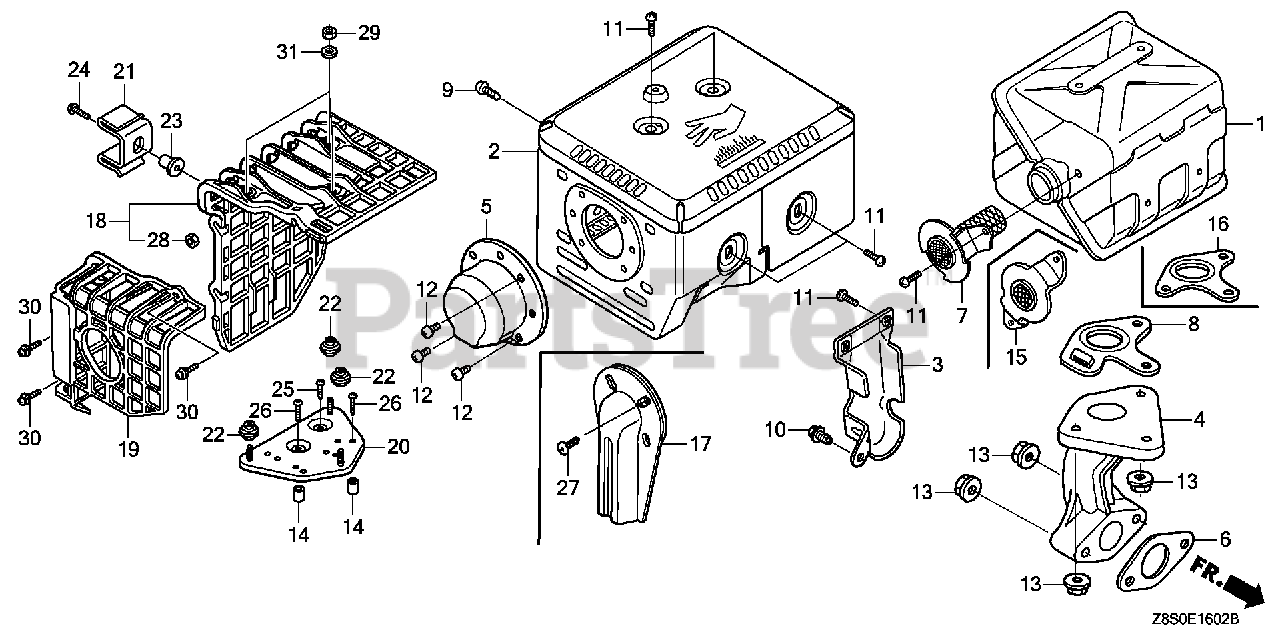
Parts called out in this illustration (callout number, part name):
1	MUFFLER
2	PROTECTOR, MUFFLER
3	PROTECTOR, EX. PIPE
5	CAP, MUFFLER
6	GASKET, EX. PIPE
7	ARRESTER, SPARK
8	GASKET, MUFFLER (ARRESTER)
8	GASKET, MUFFLER (ARRESTER)(THAI LEAKLESS)
9	SCREW, TAPPING (6X10)
10	BOLT, FLANGE (6X12) (CT200)
11	SCREW, TAPPING (5X8)
12	SCREW, TAPPING (4X6) (TO INSTALL OPTIONAL SPARK ARRESTER)
13	NUT, FLANGE (8MM)
